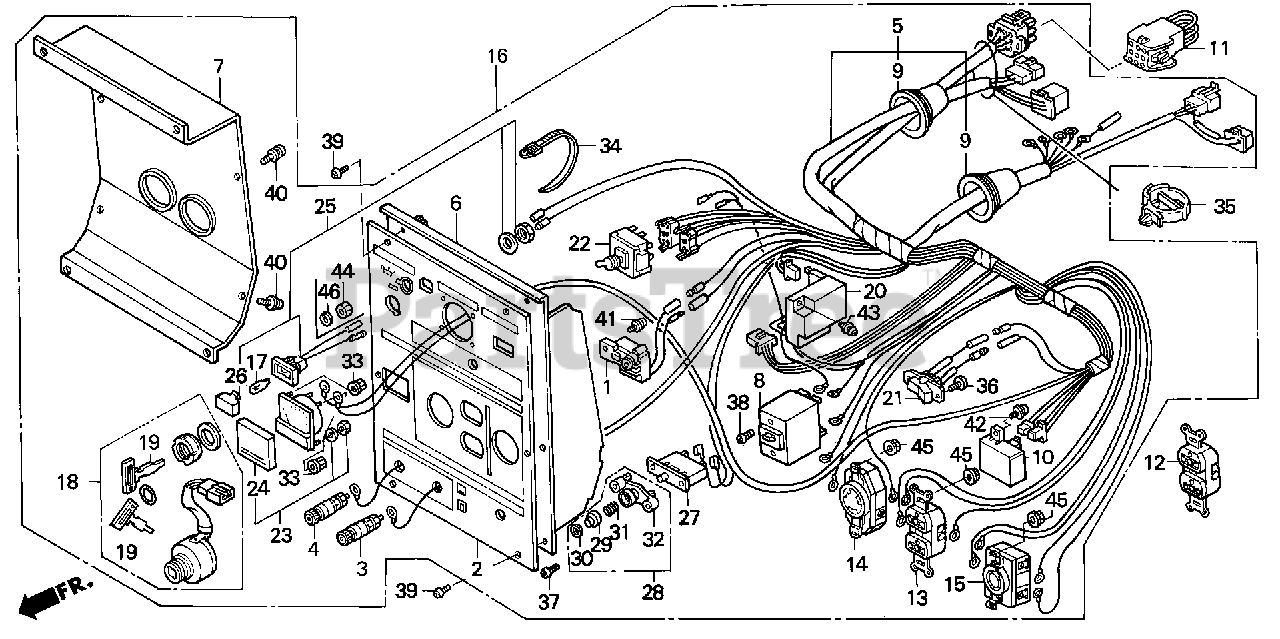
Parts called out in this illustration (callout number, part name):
1	ALERT UNIT, OIL (NOT AVAILABLE)
2	PLATE, CONTROL INDICATION
3	TERMINAL, D.C. OUT (+)
4	TERMINAL, D.C. OUTPUT (-)
5	HARNESS ASSY., CONTROL
6	PANEL, CONTROL (EXS-A)
7	COVER, CONTROL
8	BREAKER, CIRCUIT (13.5A)
9	GROMMET, MAIN WIRE
10	DIODE ASSY.
11	CONNECTOR ASSY.
12	RECEPTACLE ASSY. (125V-20A) (MATSUSHITA)
12	RECEPTACLE (20A/125V)
13	RECEPTACLE (20A/125V) (MATSUSHITA)
14	RECEPTACLE (3-PRONG) (30A/125V)
15	RECEPTACLE (20A-125/250V) (MATSUSHITA) (NOT AVAILABLE)
16	PANEL ASSY., CONTROL
17	BULB, WEDGE BASE (12V/2W) Use from Frame SN 1001725.
18	SWITCH ASSY., COMBINATION
19	KEY
20	THROTTLE UNIT, AUTO (SAWAFUJI)
21	SWITCH, AUTO THROTTLE
22	SWITCH ASSY., VOLT CHANGE
23	METER ASSY., VOLT (300V)
24	LENS, METER
25	SOCKET ASSY., LAMP (GREEN) Use from Frame SN 1001725.
26	LENS (GREEN) Use from Frame SN 1001725.
27	PROTECTOR, CIRCUIT (D.C.)
28	LENS ASSY., PROTECTOR
31	SPRING, COIL
32	HOLDER, LENS
33	NUT, FLANGE (3MM) Use from Frame SN 1001725.
34	TIE, CABLE (NATURAL 225X5.0)
35	STRAP, WIRE HARNESS (25MM) (BLACK)
36	SCREW, PAN (3X6)
37	SCREW, PAN (3X12)
38	SCREW, PAN (4X6)
39	SCREW, PAN (5X10)
40	SCREW-WASHER (4X8)
41	SCREW-WASHER (4X10)
42	SCREW-WASHER (4X12) Use up to Engine SN 2056819.
43	SCREW-WASHER (5X12)
44	NUT, HEX. (3MM)
45	NUT, FLANGE (4MM)
46	WASHER, SPRING (3MM)
